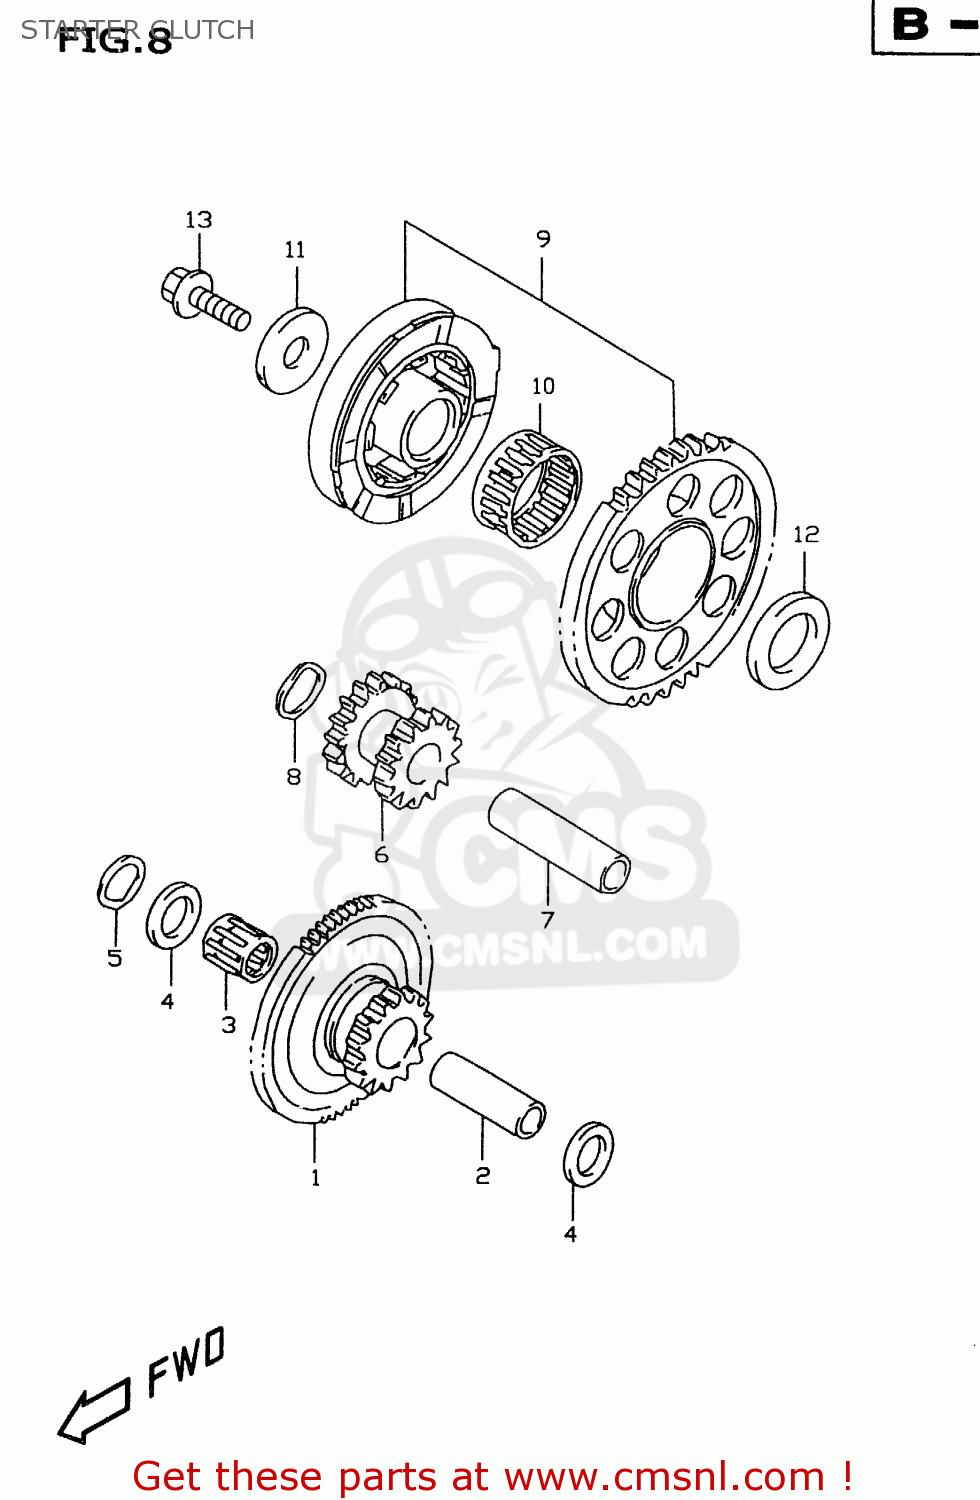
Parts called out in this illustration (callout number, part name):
1	GEAR,STARTER IDLE NO.1
2	PIN,PISTON
3	BEARING(12X16X16)
4	WASHER
5	WASHER
6	GEAR,STARTER IDLE NO.2 (N
7	PIN ,PISTON
8	WASHER
9	CLUTCH SET,STARTER
10	BEARING(28X34X16.8)
11	WASHER
12	WASHER
13	BOLT(10X23)
